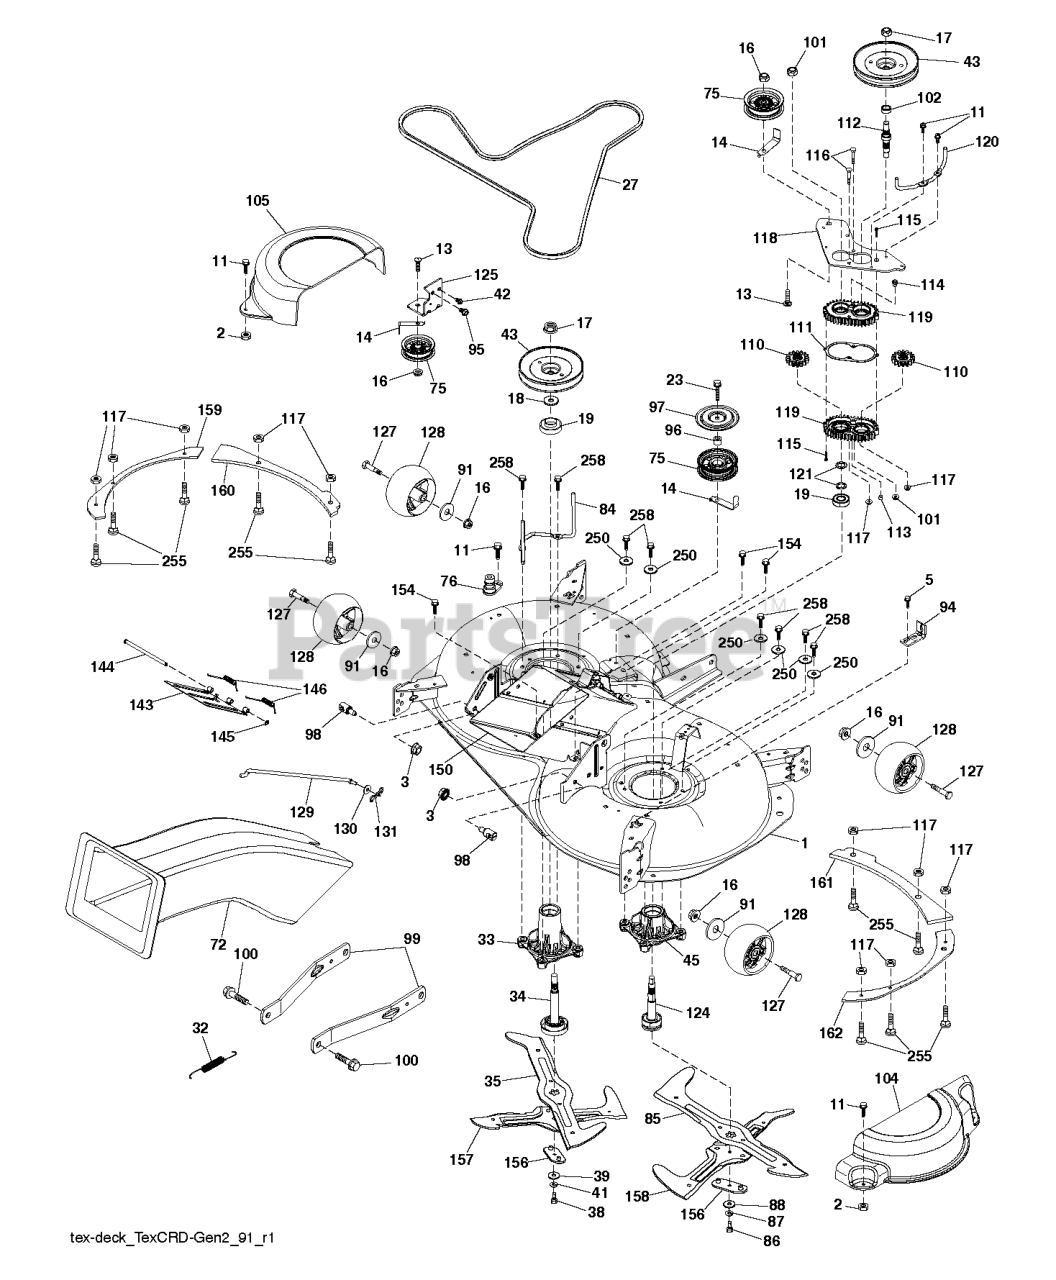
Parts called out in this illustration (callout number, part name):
1	DECK SVC 107HP.EZMUL.498
2	PALNUT 1/4
3	NUT LOCK HEX FLANGE 5/16-18
5	BOLT.5/16HEX.WHS.HD
11	SCREW.1/4-20X5/8
13	BOLT.3/8-16X1.50
14	KEEPER, BELT IDLER
16	NUT LOCK FLG 3/8-16 UNC
17	NUT.FLANGE.LOCK.TOP
18	WASHER.SPACER.MANDREL
19	BEARING.MANDREL.TOP.EXTENDED
23	SCREW LT
27	BELT.ELECT.MOWER.DRIVE 97.8 EL
32	SPRING 107CM & 97CM ELECTRIC D
33	RP.HOUSING.MANDREL.4PT.
34	SHAFT ASM.MNDRL.N/GREASEABLE
35	BLADE.3N1.LH.CRD
38	BOLT.BLADE.7/16-20 X 1.5 GR8
39	WASHER.7/16.FLAT
41	WASHER 7/16 LOCK
42	SCREW
43	PULLEY PULLEY MANDREL 5.438 PD
45	HOUSING.MANDREL.44/46" VENT
72	RP.CHUTE 107/97 TEX GENII
75	FLAT IDLER PULLEY
76	PORT.WASHOUT
84	KEEPER KEEPER. LH MANDREL BELT
85	BLADE.3N1.RH.CRD
86	BOLT.3/8-24X1.25GR8. LHTHRD
87	SLW 3/8 STD
88	WASHER.BLADE
91	WASHER
94	BRKT.CLUTCH.CABLE
95	SCREW, 3/8-16X3/4
96	SPACER
97	PROTECTOR
98	STUD.FASTNER.W/ANTI-ROTATE
99	ARM.SUSPENSION.MOWER.R
100	BOLT.SHOULDER
101	NUT.CROWNLOCK.9/16 -18.UNC
102	SPACER BEARING
104	COVER.MANDREL.107.RH.GEN.2
105	COVER.MANDREL.107.LH.GEN.2
110	CRD.SPUR.GEAR
111	GASKET GASKET GEARCASE
112	SHAFT SHAFT. CRD GEARCASE ADAP
113	PLUG PLUG OIL
114	VENT.BREATHER.1/8 NPT
115	SCREW
116	BOLT.CARIGE.SS.1/4-20X1.75GR5
117	NUT T
118	ARM ARM. CLUTCHING 107 TEX CRD
119	GEARCASE GEARCASE SUBASM
120	KEEPER KEEPER. RH MANDREL BELT
121	WASHER WASHER
124	MANDREL SHAFT NON/GREASE
125	BRACKET
127	BOLT.SHOULDER.3/8-16X3-5/8.
128	RP WHEEL. GUAGE RALLY
129	ROD ROD. SWAY CRD GEN II
130	WASHER
131	PIN.COTTER.5/16.BOW TI
143	COVER DOOR.107 CM CRD EZ MULCH
144	PIN PIN.HINGE
145	E-RING.5/16"
146	SPRING SPRING: EZ MULCH DOOR
150	CHUTE LOWER.WLDT.107.CRDII
154	SCREW T-30 1/4-20 X
156	ADAPTER ADAPTER.CROSSBLADE.107
157	BLADE 107CM.CROSS.BLADE
158	BLADE.CROSS.RH.CRD.107
159	REINFORCE.PLATE.LH.FT.X431
160	REINFORCE.PLATE.LHS.BOLT.431
161	REINFORCE.PLATE.RH.FRT.X431
162	REINFORCE.PLAT.RH.SD.BLT.X431
255	RHSNB, 1/4-20 X 1, GR5
258	BOLT.HEX.WASHR.HED.313-18X1.19
